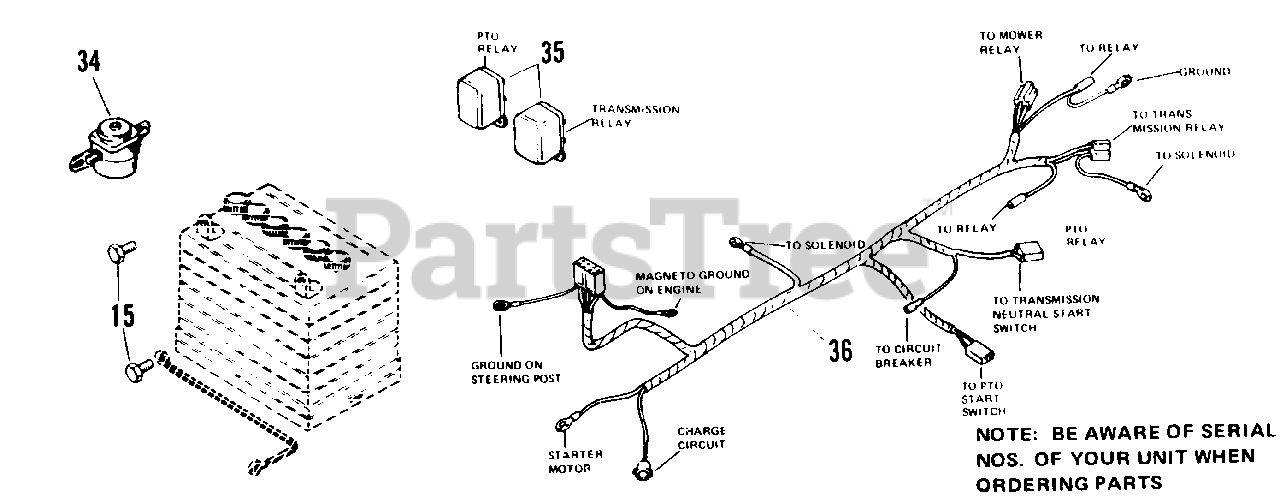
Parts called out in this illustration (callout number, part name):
15	CAPSCREW, Hex Hd., 1/4-20 x 3/4 (6008)
34	SOLENOID (03566)
35	RELAY, 12 Volt (03566)
36	HARNESS, Lower (Replaced by 1663065)(03566)
